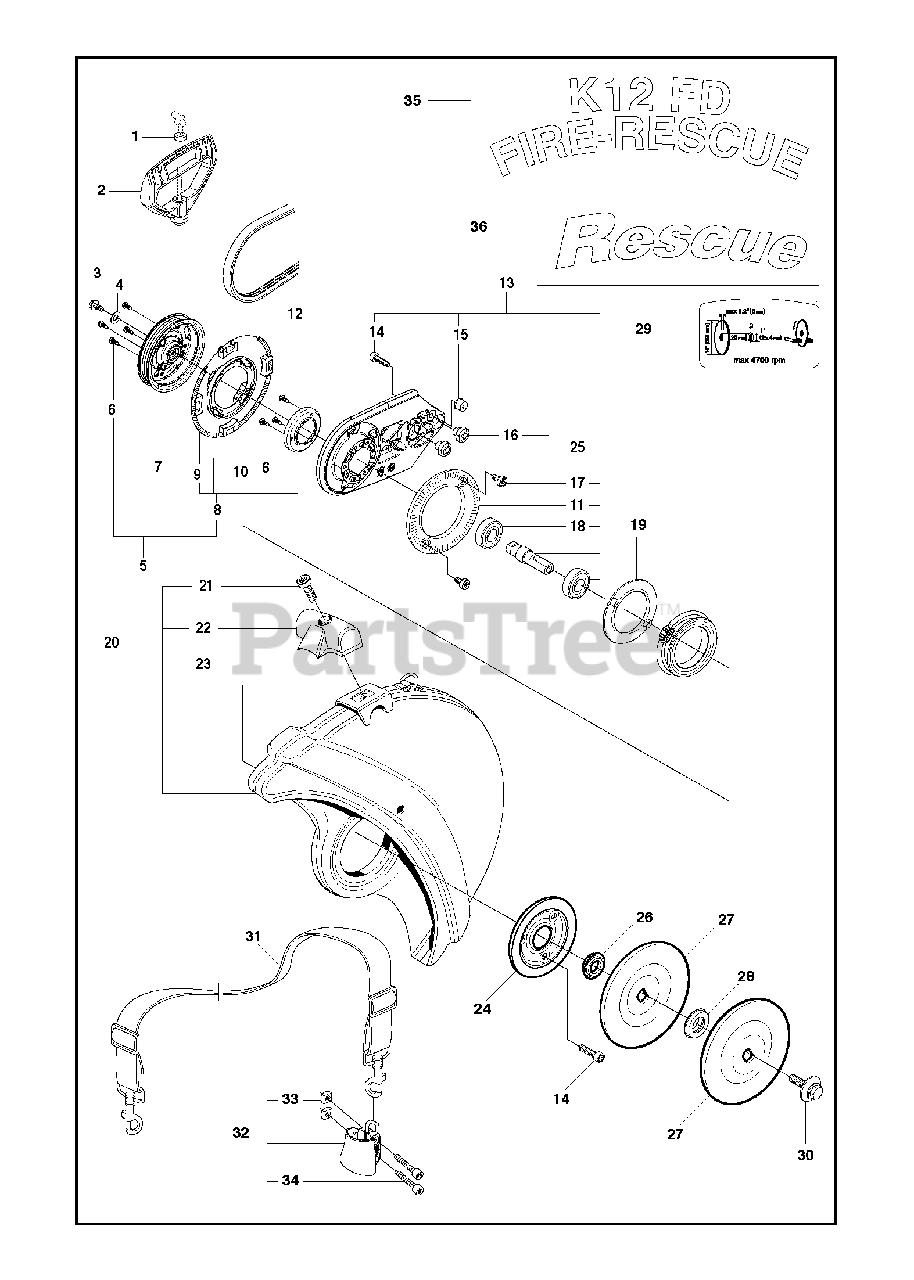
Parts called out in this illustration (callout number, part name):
2	STARTER HANDLE
5	PULLEY ASSY
6	SCREW CITXPANT
13	BEARING HOUSING
14	SCREW ITXSCM
15	TORSION STOP
17	SCREW ITXSCM
18	BALL BEARING
20	BLADE GUARD"14"""
21	SCREW ITXSCM
25	BEARING HOUSING
26	SUPPORT FLANGE
27	FLANGE WASHERJapan
28	BUSHINGJapan
29	DECAL"14"""
29	DECAL"12"""
34	SCREW ITXSCM
